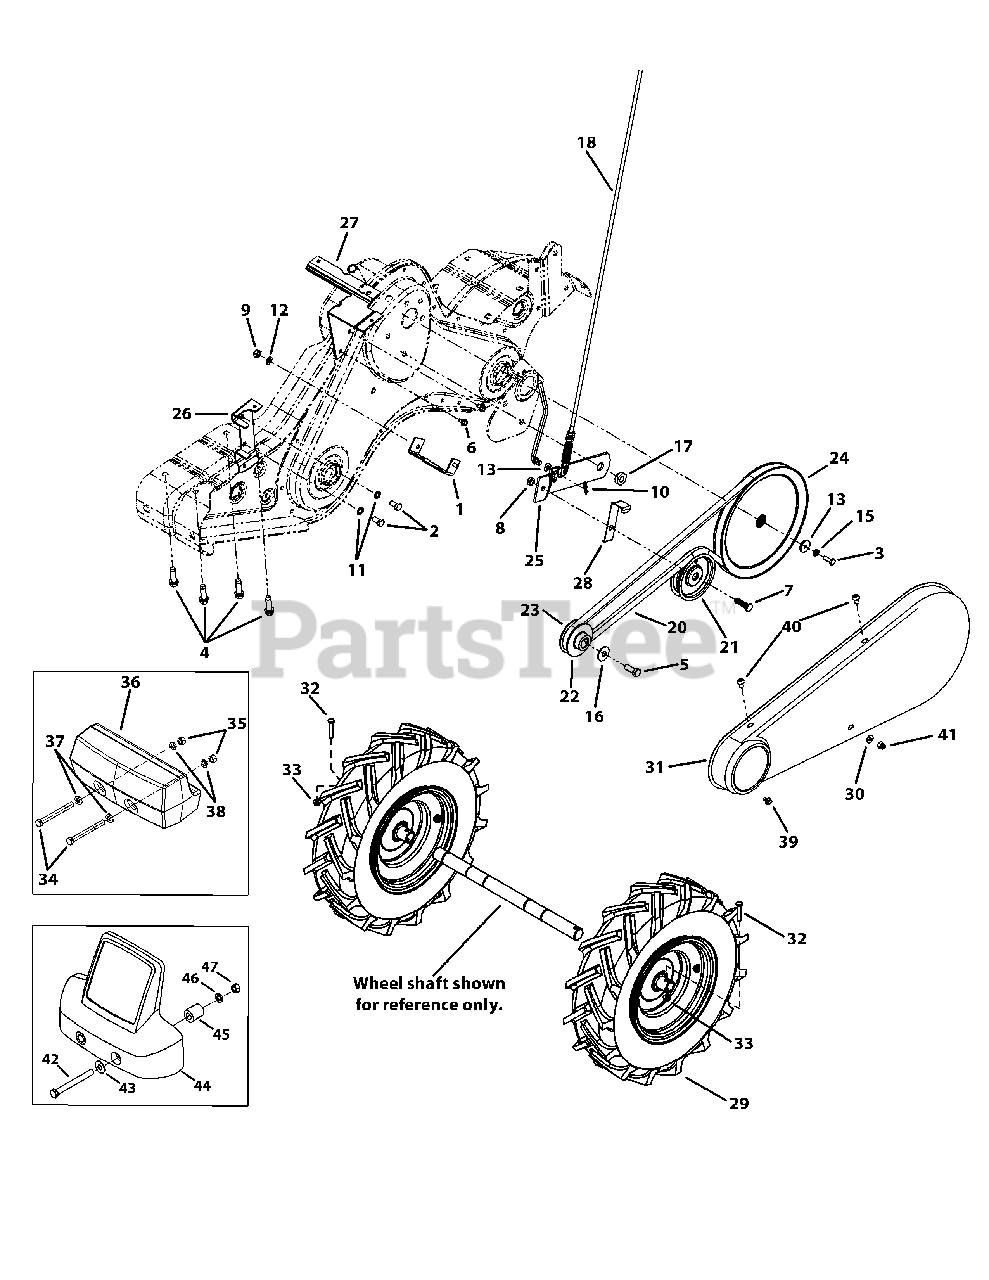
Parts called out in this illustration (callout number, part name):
1	Belt Cover Brkt Ass’y
2	Hex Hd Cap Screw 5/16-24 x .625 Gr. 5
3	Hex Hd Cap Screw1/4-28 x .625
4	Hex S-Tapp Scr 3/8-16 x 1.5 Gr. 5
5	Hex L-Scr 3/8-24 x 1.00" Lg. Gr. 8
6	Hex Wash S-Tapp Scr 1/4-20 x .625
7	Hex Screw 3/8-16 x 1.25 Gr. 5
8	Hex Cent L-Nut 3/8-16 Gr. 5
9	Flanged Lock Nut 5/16-18 Gr. 5
10	Int. Cotter Pin 5/16 Dia.
11	Internal L-Washer
12	L-Wash 5/16 ID
13	Flat Washer .25 ID x .93 OD x .125
14	Shakeproof Spring Washer
15	L-Wash 1/4 ID
16	Belleville Washer
17	Shoulder Nut
18	Clutch Cable
19	Idler Pulley Rod
20	Belt: 4L x 58.16" Lg.
21	Flat Idler w/flanges 3-3/4" OD
22	Outer Engine Pulley Half
23	Inner Engine Pulley Half
24	Input Pulley
25	Idler Bracket
26	Belt Keeper Brkt.
27	Shift Cover Brkt.
28	Idler Belt Keeper
29	Wheel Ass’y 16.0 x 4.6 x 8
30	Flat Washer .266 ID x .625 OD
31	Belt Cover
32	Hex Cap Screw 1/4-20 x 1.5" Lg. Gr. 8
33	Flange Locknut 1/4-20
34	Hex Bolt 1/2-13 x 5.00" Lg.
35	Hex Nut 1/2-13
36	Counterweight 40 Lbs.
37	Flat Washer .510 ID x 1.0 OD x .125
38	L-Washer 1/2" ID
39	Hex Wash HD Tapp Scr 1/4-20 x .38
40	Torx Mach. AB-Tapp Scr. 1/4 x .62" Lg.
41	Hex Lock Stop Nut 1/4-28
42	Hex Hd. Scr. 1/2-13 X 5.5
43	Flat Washer 1/2 x 1.25 x .100
44	Counterweight
45	Hub, .636 ID x 1.0 OD x .94
46	Lockwasher 1/2
47	Hex Nut 1/2-20
